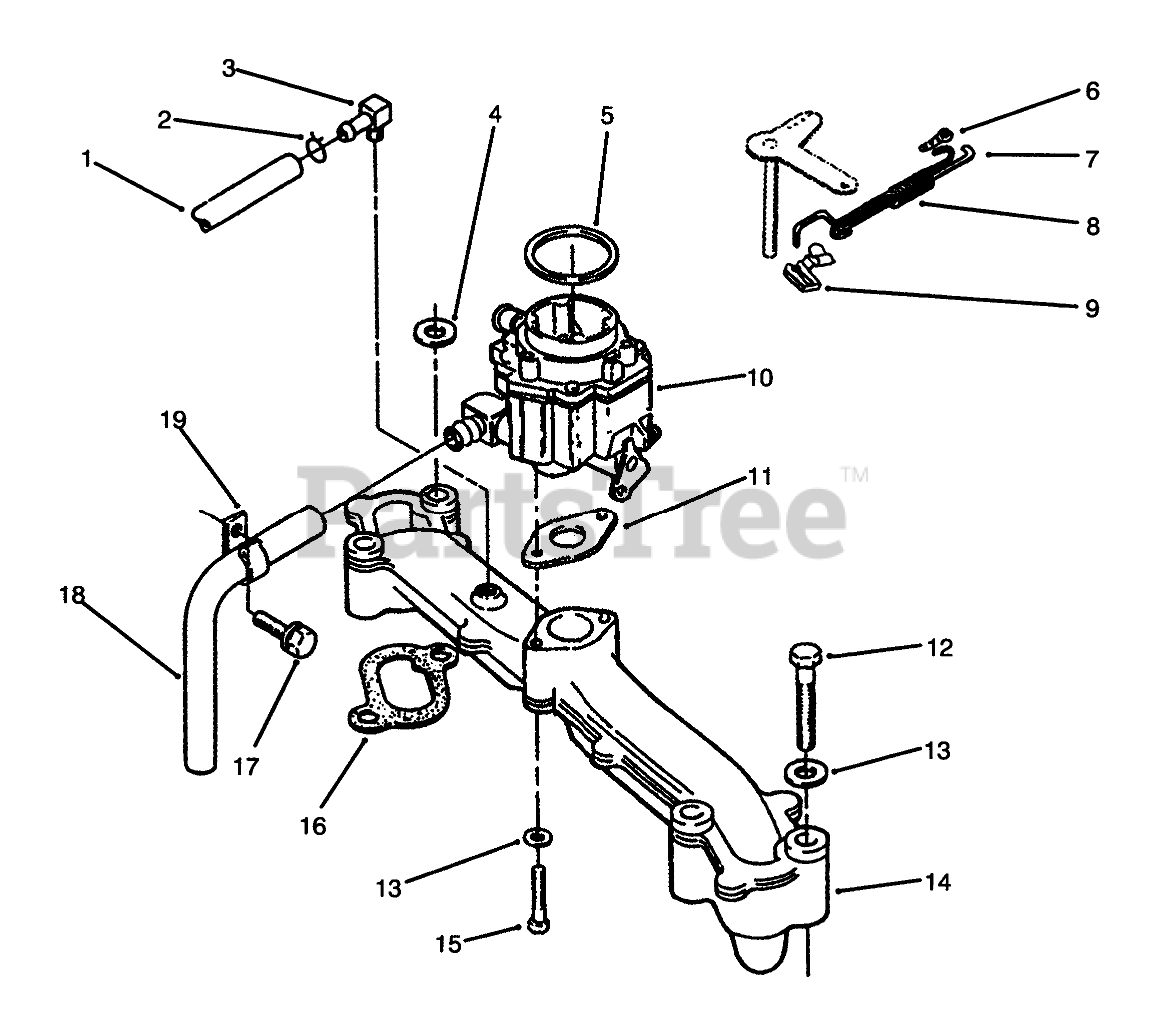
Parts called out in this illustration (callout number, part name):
1	HOSE-RUBBER, BREATHER
2	CLAMP-HOSE
2	CLAMP-HOSE, BREATHER
3	FITTING-BARB
4	FLAT WASHER
5	SEAL
6	CLIP
7	Governor Control Rod
8	Spring-Governor Rod
9	CLIP
10	Assembly-Carburetor Before Serial No. 59000178 (Incl. Ref. #5 & 11)
11	GASKET-CARBURETOR
12	HHCS
13	WASHER-FLAT
14	MANIFOLD
15	HEX-HEAD CAP SCREW
16	GASKET
17	SCREW-HWH
18	FUEL HOSE
19	CLIP-WIRE
